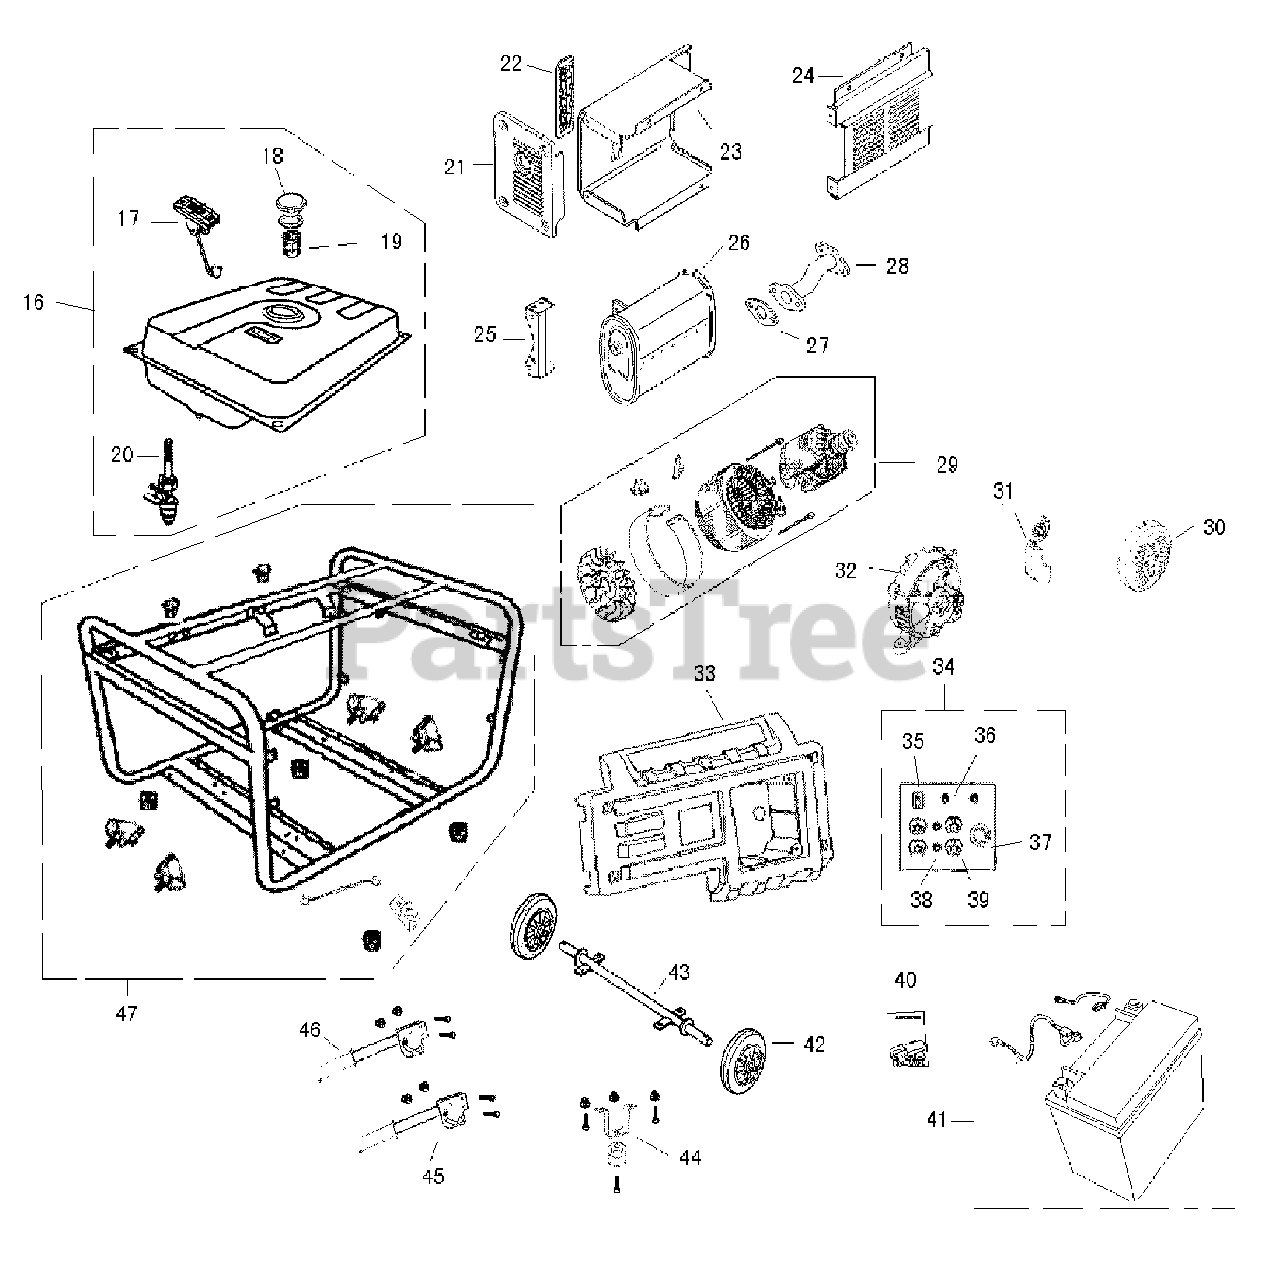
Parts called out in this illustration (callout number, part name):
16	TANK COMP., FUEL
17	METER COMP., FUEL
18	CAP COMP.,FUEL FILLER
19	FILTER, FUEL TANK
20	COCK COMP., FUEL
21	PROTECTOR, MUFFLER SIDE
22	SEAL, PROTECTOR MUFFLER
23	PROTECTOR COMP., MUFFLER
24	PROTECTOR COMP., MUFFLER
25	STAY, MUFFLER
26	MUFFLER ASSY.
27	GASKET,MUFFLER
28	PIPE, COMP., EX.
30	COVER GENERATOR END
31	AUTOMATIC VOLTAGE REGULATOR
33	CASE, CONTROL PANEL
34	CONTROL PANEL ASSY.
35	SWITCH ASSY., COMBINATION
36	CIRCUIT BREAKER
37	SOCKET,L14-30
39	CIRCUIT BREAKER
40	OPERATORS MANUAL
41	BATTERY ASSY.
43	SHAFT COUP., WHEEL
45	HANDLE ASSY. , R
46	HANDLE ASSY., L
